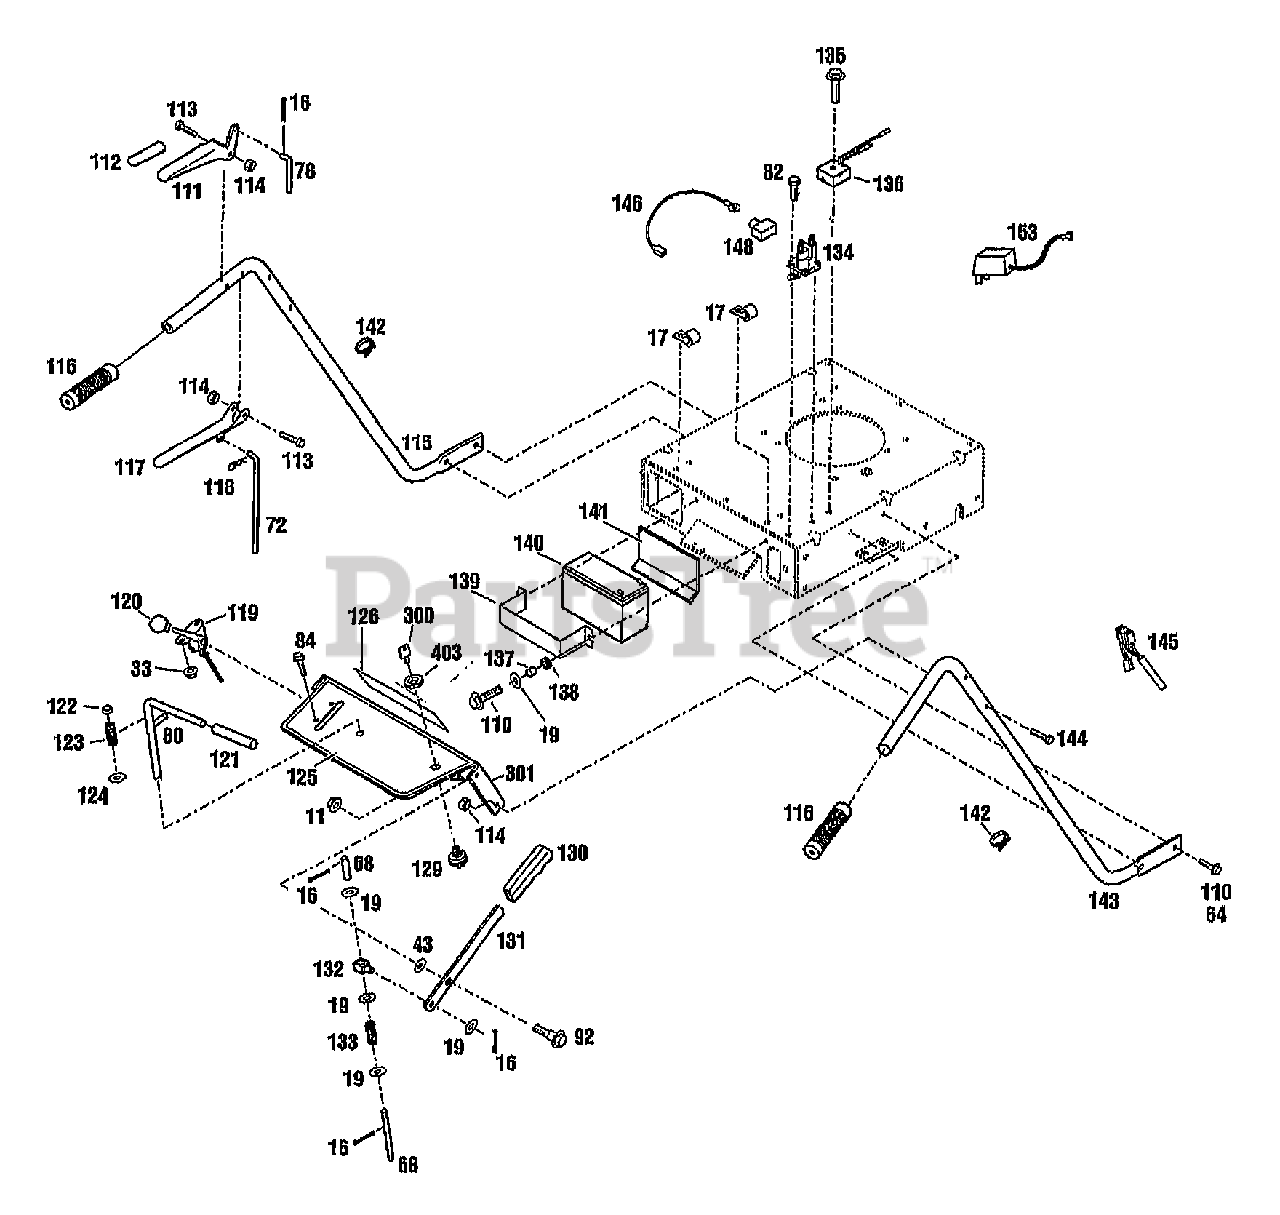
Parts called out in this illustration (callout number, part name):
11	NUT-HFLK 3/8-16
16	PIN-COTTER .093X.625
17	CLIP-J {34037,34039}
19	WASHER-FLAT 5/16 SAE
33	NUT-HF/LK 1/4-20
43	WASHER-FLAT 1.0X.516X.031
64	NUT-HFLK 5/16-18
68	ROD-UPPER BLADE
72	ROD-UPPER TRANS MOWER
78	ROD-UPPER BRAKE
80	ASSM-SHIFT LEVER
82	SCR 1/4-20X.5 FL SELF TAP {34039}
84	SCR-HFLK 1/4-20X.50
92	BOLT-SHOULDER MOWER
110	SCR-HFLK 5/16-18X.75
111	KIT-HANDLE ASSM
112	DECAL-OPC MOWERS
113	SCR-HH 1/4-20X1.5 G5
114	NUT-HT LK 1/4-20
115	HANDLEBAR-LH
116	GRIP-FLEX
117	HANDLE-CONTROL MOWER
118	PIN-CLIP .08
119	CONTROL-THROTTLE {34037,34036}
119	CABLE-THROTTLE CONTROL {34038,34039}
120	KNOB
121	GRIP-HANDLE
122	BUSHING-.5X.21 NYLON FLNG
123	SPRING
124	WASHER-1.06X.531X.1
125	DECAL-WARNING {34037}
125	DECAL-WARNING {34038}
125	DECAL-WARNING {34039}
125	DECAL-WARNING {34036}
126	DECAL-T/B HIGH WHEEL
129	SWITCH-IGNITION 5.5HP {34037}
129	ASSM-KEYSWITCH {34039}
130	GRIP-HANDLE
131	LEVER-MOWER ENGAGE
132	BLOCK-PIVOT
133	SPRING-COMPRESSION
134	SOLENOID {34039}
135	SCR-HFLK {34039}
136	REGULATOR {34039}
137	SPACER {34037,34039}
138	GROMMET {34037,34039}
139	BRACKET-BATTERY {34037,34039}
140	BATTERY {34037,34039}
141	PAD-BATTERY {34037,34039}
142	TIE-CABLE NYLON BLACK
143	HANDLEBAR-RH
144	SCR-HH 1/4-20X1.75 G5
145	HARNESS-MAIN USE1770370 {34037}
145	HARNESS-WIRING {34039}
146	ASSM-WIRE LEAD {34039}
148	BOOT-CABLE {34039}
153	CHARGER-BATTERY {34037,34039}
300	KEY-IGNITION
301	ASSM-CONSOLE {34037}
301	ASSM-CONSOLE 26" 3 SPD {34038}
301	ASSM-CONSOLE 26" EL 3 SPD {34039}
301	ASSM-CONSOLE 22" 3 SPD {34036}
403	NUT-IGNITION SWITCH
